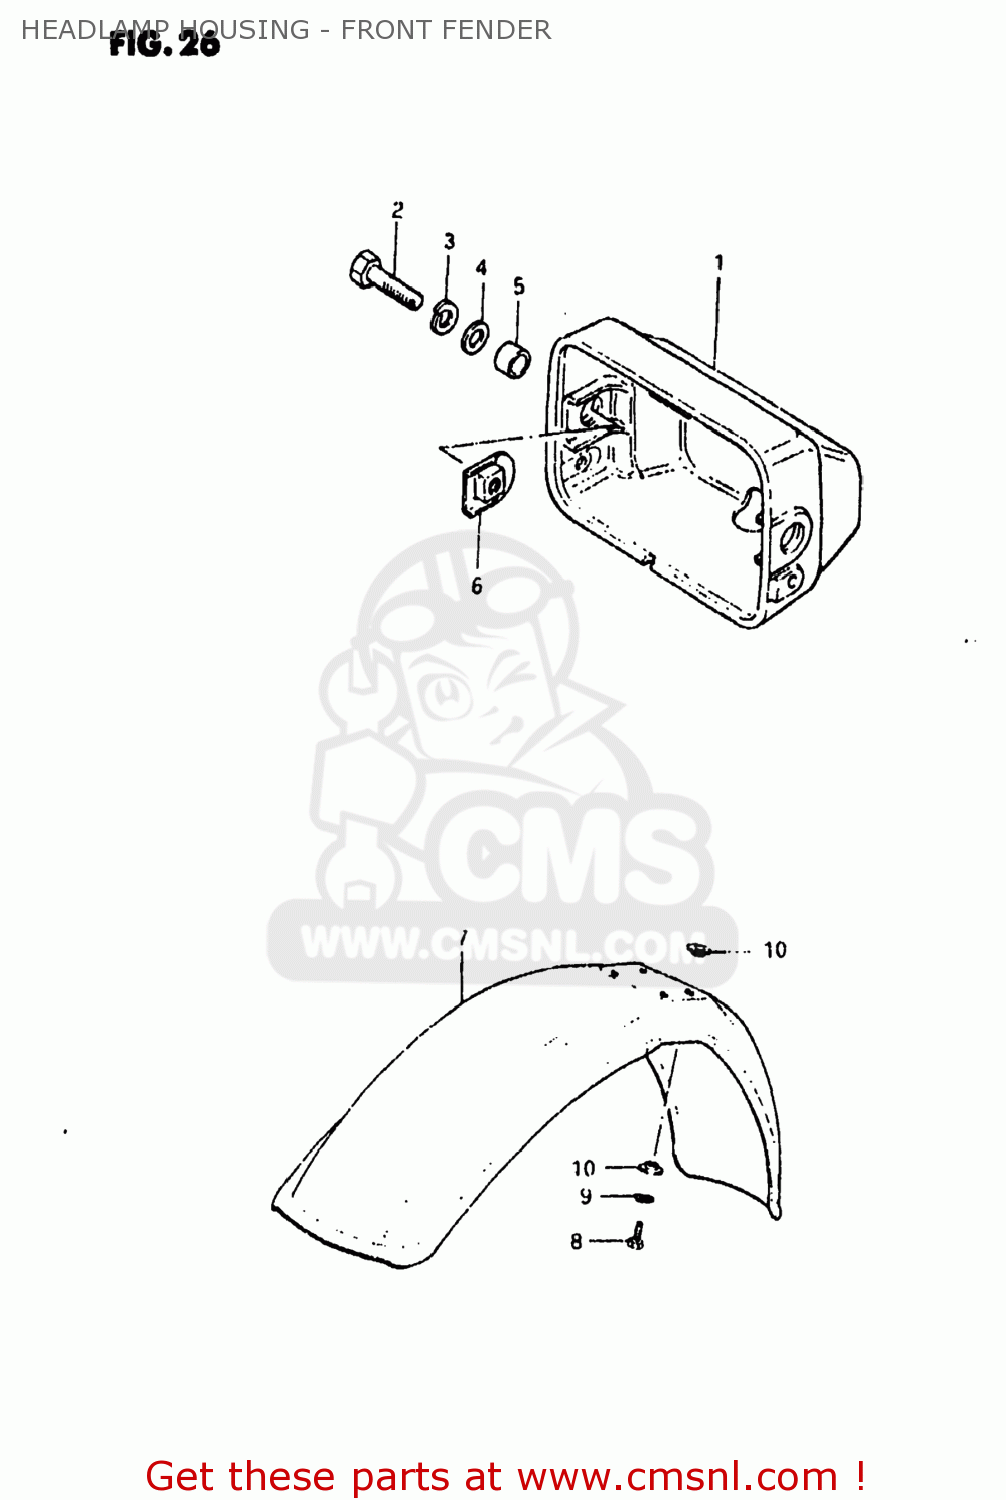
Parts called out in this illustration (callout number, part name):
1	HOUSING,HEADLAMP
2	BOLT
3	LOCK WASHER
4	WASHER
5	SPACER (8.8X12X7)
6	PLATE,HEADLAMP HOUSING
7	FENDER,FRONT
8	BOLT, UPPER
9	LOCK WASHER
10	WASHER
